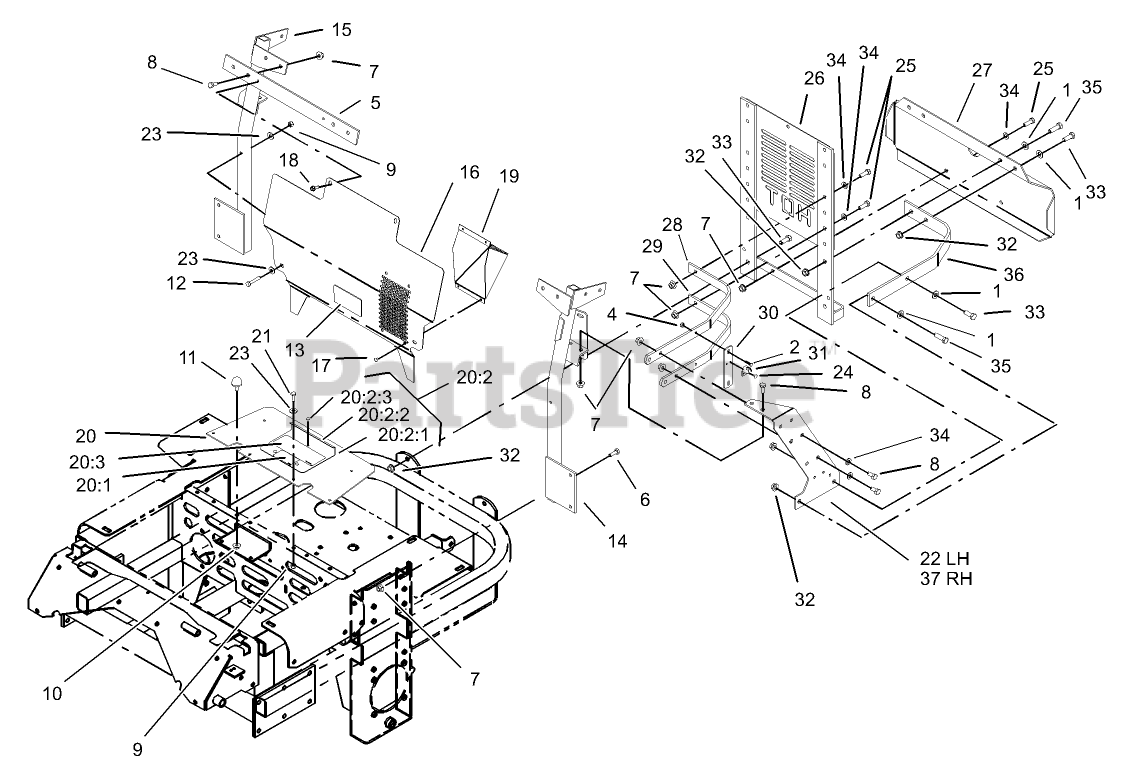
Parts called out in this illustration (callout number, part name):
1	WASHER-FLAT
2	SCREW-HEAD, TRUSS
4	NUT-LOCK, NI
5	CROSSBAR
6	SCREW-HH
7	NUT-HF
8	SCREW-HH
9	NUT-LOCK, NI
10	NUT-HF
11	BUMPER
12	SCREW-HH
13	DECAL-ROUTING, BELT
14	Brace-Radiator, LH
15	BRACE-RADIATOR, RH
16	Deflector-Air
17	RIVET-POP
18	SCREW-HWHTF
19	Plenum-Intake, Air
20	SHIELD ASM
20:1	DECAL-IMPORTANT
20:2	SHIELD AND LIFT ASM
20:2:1	SHIELD-ENGINE
20:2:2	LIFT-SHIELD
20:2:3	RIVET-POP
20:3	DECAL-DEVICES, ROTATING
21	SCREW-HH
22	PLATE-SIDE, LH
23	WASHER-FLAT
24	RIVET
25	SCREW-HH
26	MOUNT-RADIATOR, REAR
27	GUARD-BUMPER
29	RIB-BOTTOM
30	BAR-HOOK, LATCH
31	KEEPER-LATCH, RUBBER
32	NUT-HHF, WHIZ
33	SCREW-HH
34	WASHER-PLAIN
35	SCREW-HH
36	BAR-RADIATOR MOUNT FRAME
37	PLATE-SIDE, RH
